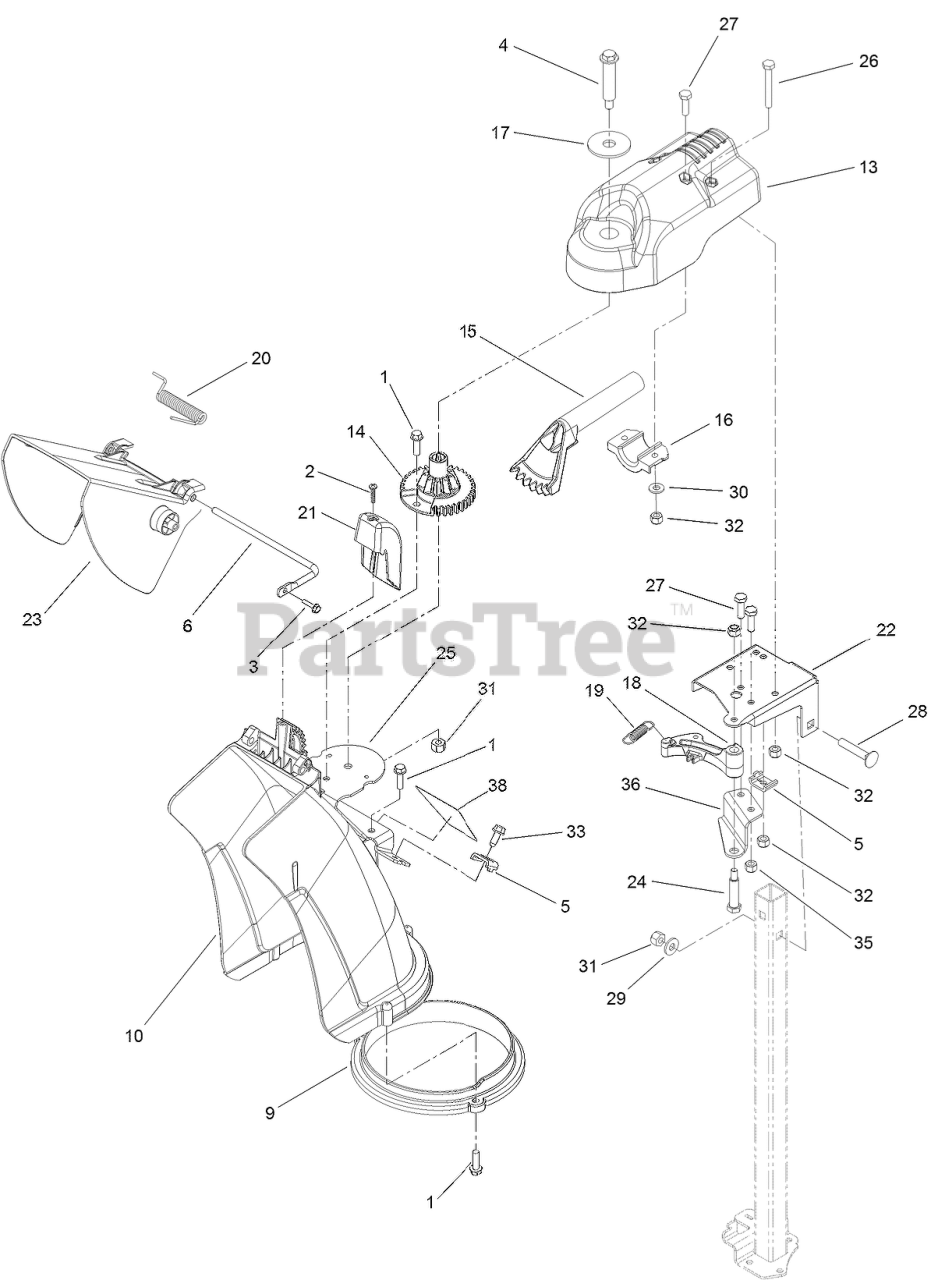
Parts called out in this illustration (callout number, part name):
1	SCREW-PLASTITE, HWH
2	SCREW-PPH
3	SCREW-PLASTITE, HWH
4	BOLT-SHOULDER
5	CLAMP-CABLE
6	ROD-DEFLECTOR
9	RING-CHUTE
10	CHUTE-DISCHARGE
13	MOUNT-CHUTE, DISCHARGE
14	GEAR-CHUTE
15	GEAR-BEVEL
16	MOUNT-GEAR, BEVEL
17	WASHER-PLAIN
18	LATCH-CHUTE
19	SPRING, CHUTE LATCH
20	SPRING-TORSION
21	CHUTE-COVER
22	BRACKET-SUPPORT, CHUTE
23	DEFLECTOR-CHUTE
24	BOLT, SHOULDER
25	BRACKET-MOUNT, CHUTE
26	SCREW-HH
27	SCREW-HH
28	BOLT-CARR
29	WASHER-FLAT
30	WASHER-FLAT
31	NUT-HEX
32	NUT-HEX
33	SCREW-HWH
35	NUT-HEX
36	BRACKET-SUPPORT, LATCH
38	DECAL-GUARANTEE
